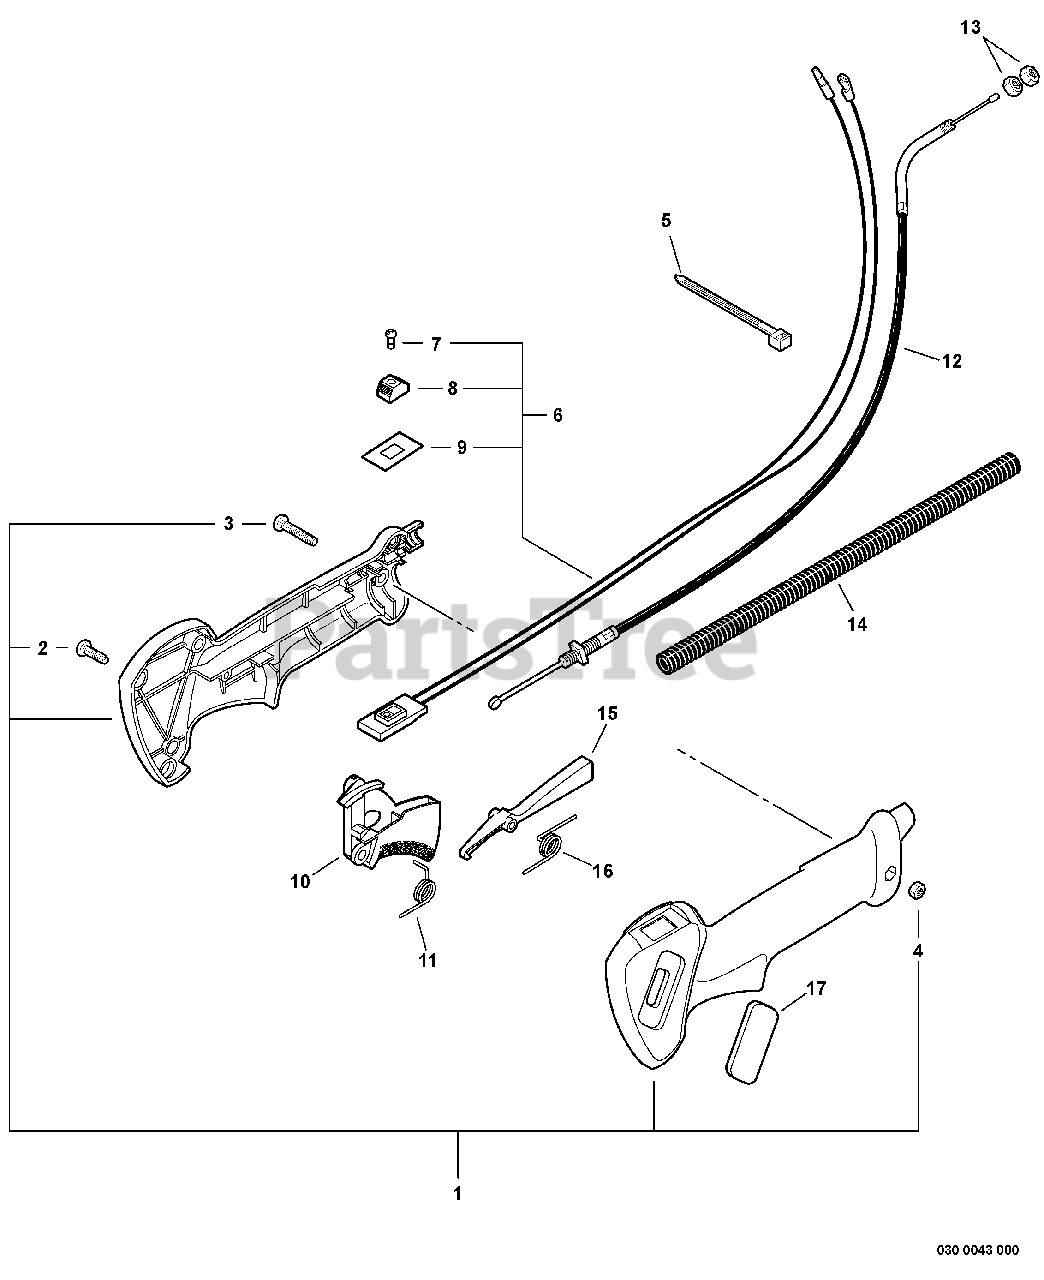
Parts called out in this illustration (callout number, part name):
1	GRIP ASSY, THROTTLE
2	SCREW 4×16
3	SCREW 5×30
4	NUT M5
5	TIE, CABLE
6	SWITCH ASSY
7	SCREW 3×10
8	KNOB, SWITCH - ORANGE
9	LABEL, SWITCH
10	TRIGGER, THROTTLE
11	SPRING, TORSION
12	CABLE, THROTTLE
14	TUBE, FLEXIBLE
15	LOCKOUT, THROTTLE
16	SPRING, TORSION
